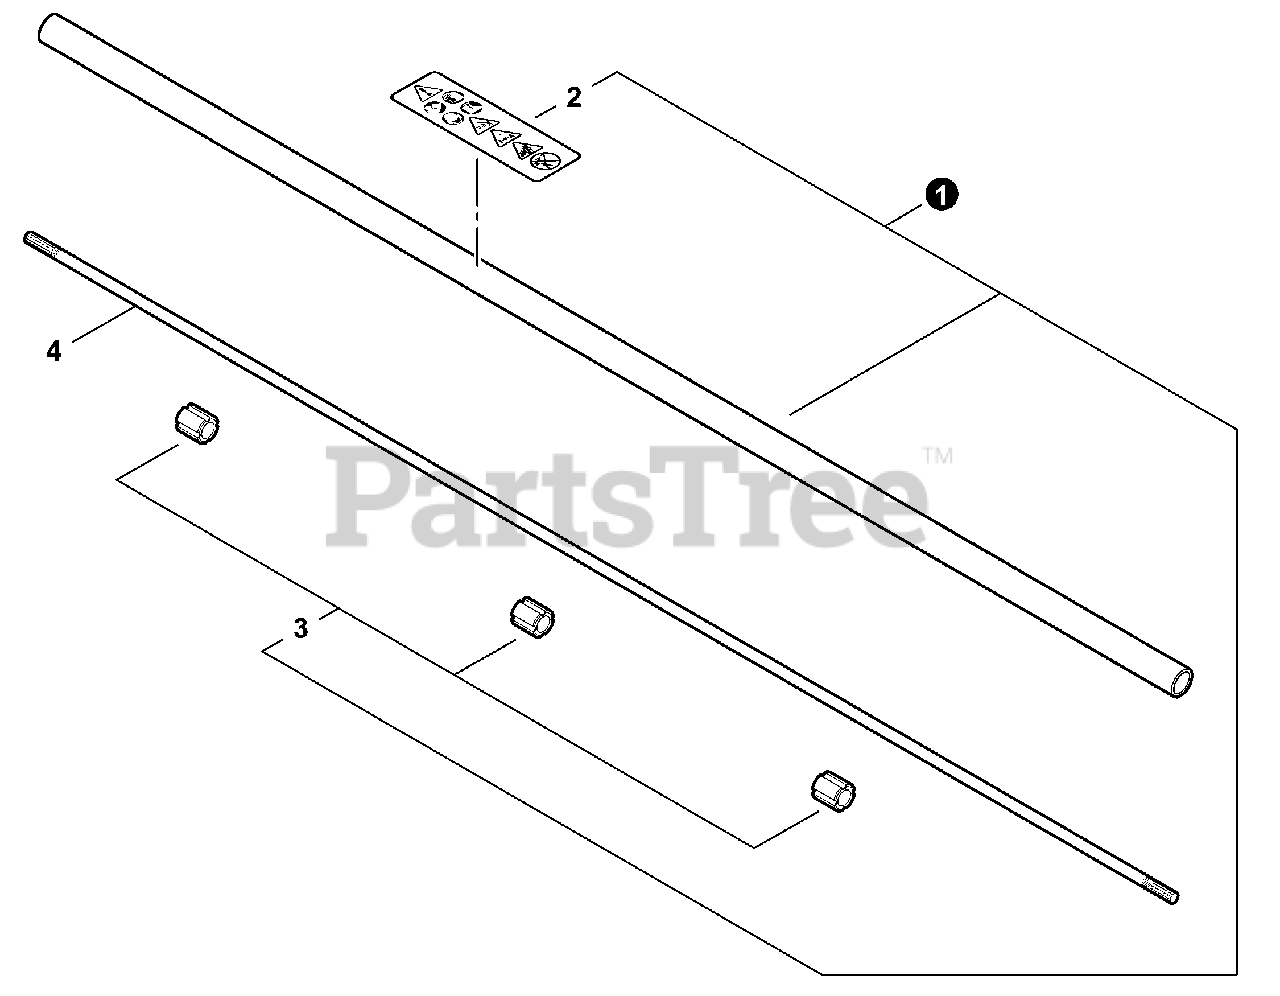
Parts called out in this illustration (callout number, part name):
1	MAIN PIPE ASSY
2	LABEL, CAUTION
3	BUSHING
4	MAINSHAFT Ø6×790 MM
